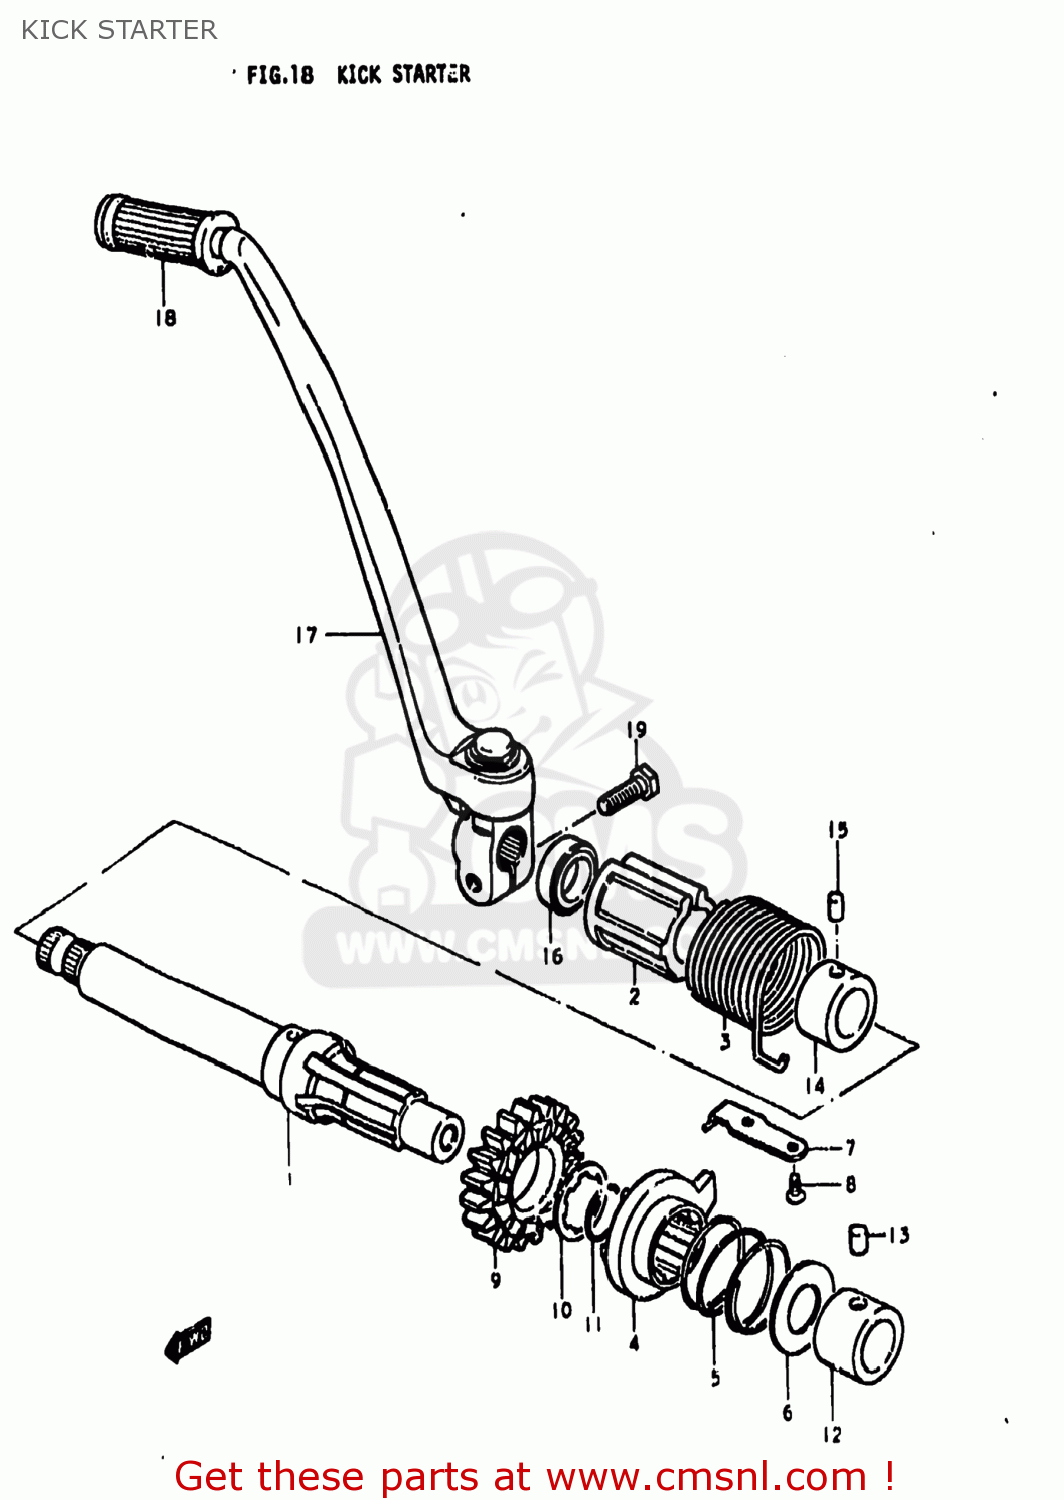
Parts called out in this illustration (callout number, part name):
1	SHAFT,KICK STARTER
2	GUIDE,KICK SHAFT SPRING
3	SPRING
4	STARTER,KICK
5	SPRING
6	WASHER
7	GUIDE,STARTING SPRING
8	SCREW
9	GEAR,KICK STARTER DRIVE
10	WASHER,LOCK
11	CIRCLIP
12	BUSHING
13	PIN
14	BUSHING
15	PIN
16	SEAL,OIL(20X27X5)
17	LEVER ASSEMBLY,KICK STARTER
18	RUBBER,KICK STARTER PEDAL
19	BOLT
